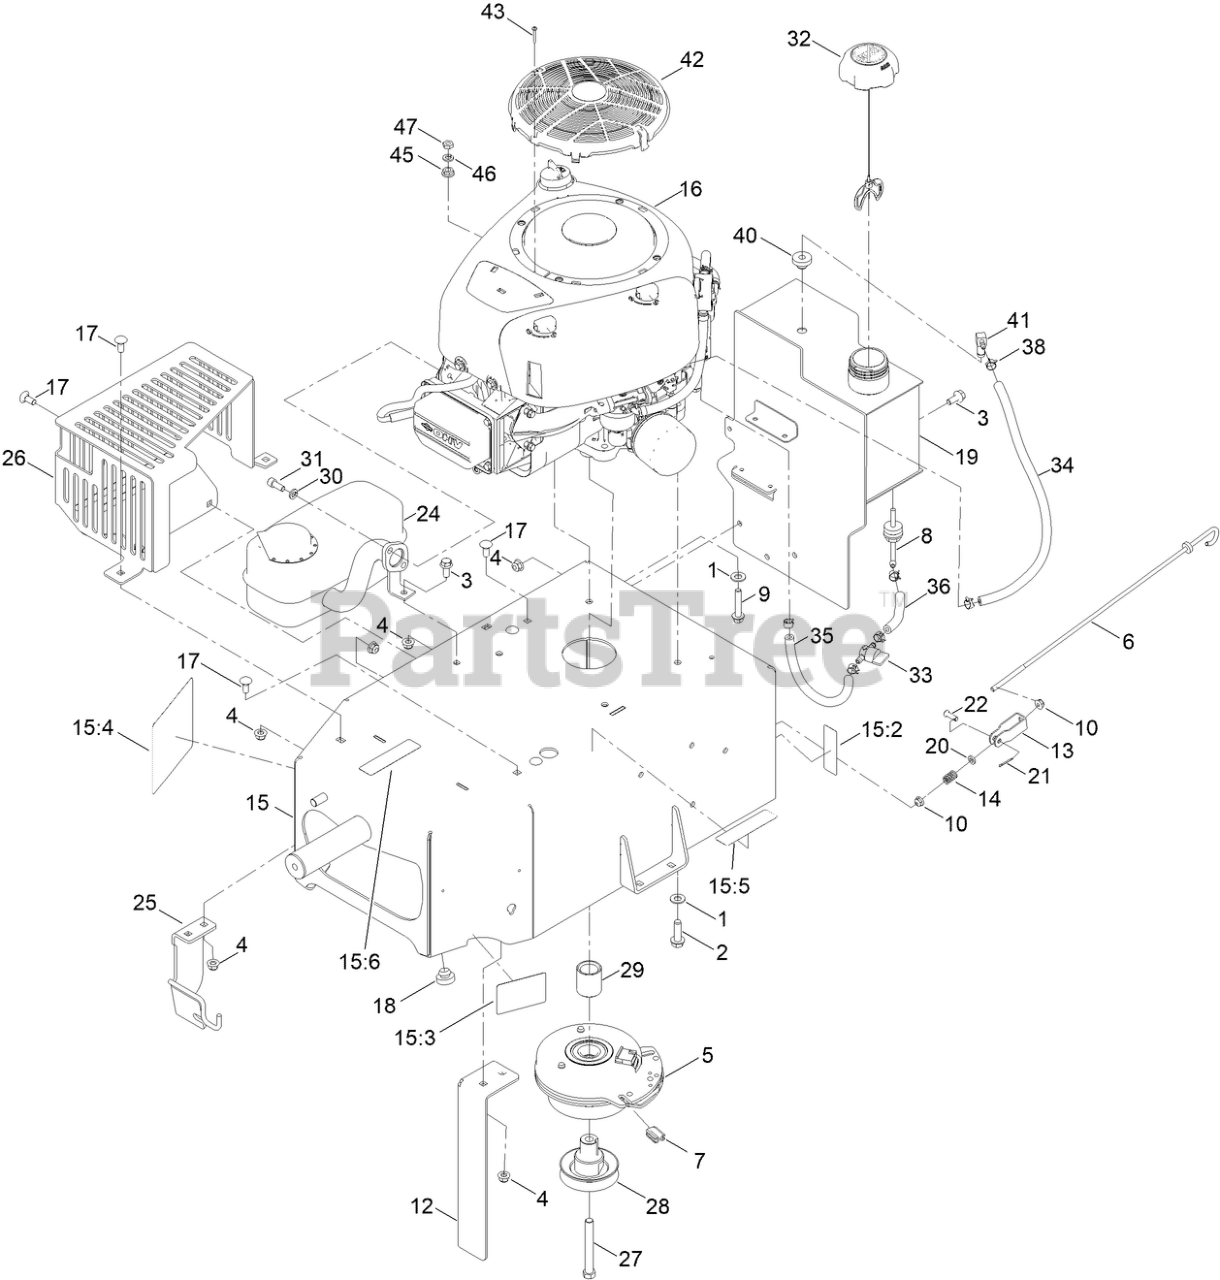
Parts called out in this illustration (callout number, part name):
1	WASHER-FLAT
2	SCREW-THD
3	SCREW-HHF
4	NUT-HF, NI
5	CLUTCH-ELECTRIC
6	ROD-BRAKE
7	ISOLATOR-CLUTCH
8	FITTING-FUEL, BULKHEAD
9	SCREW-HWH
10	NUT-HF
12	BRACKET-TORQUE
13	CLEVIS
14	SPRING-COMPRESSION
15	FRAME ASM
15:2	DECAL-BRAKE, PARKING
15:3	DECAL-BYPASS
15:4	DECAL-SERVICE
15:5	DECAL-ARRESTOR, SPARK
15:6	DECAL-HOT SURFACE
16	ENGINE-BRIGGS STRATTON PROFESSIONAL
17	BOLT-CARR
18	BUMPER-RUBBER
19	TANK-FUEL
20	SPACER-PLATE, PIVOT
21	PIN-COTTER
22	PIN-CLEVIS
24	MUFFLER, BRUSH CUTTER
25	GUIDE-BELT/CABLE
26	GUARD-MUFFLER [BLACK]
27	SCREW-HH
28	PULLEY-HYDRO
29	SPACER, CLUTCH
30	WASHER-LOCK
31	SCREW-HSH
32	CAP-FUEL
33	VALVE-FUEL
34	HOSE-FUEL
35	HOSE-FUEL
36	HOSE-FUEL
38	CLAMP-HOSE
40	BUSHING
41	FITTING-ELBOW, 90 DEG
42	COVER-FAN
43	SCREW-FAN
45	NUT-HF
46	WASHER-LOCK
47	NUT-JAM
